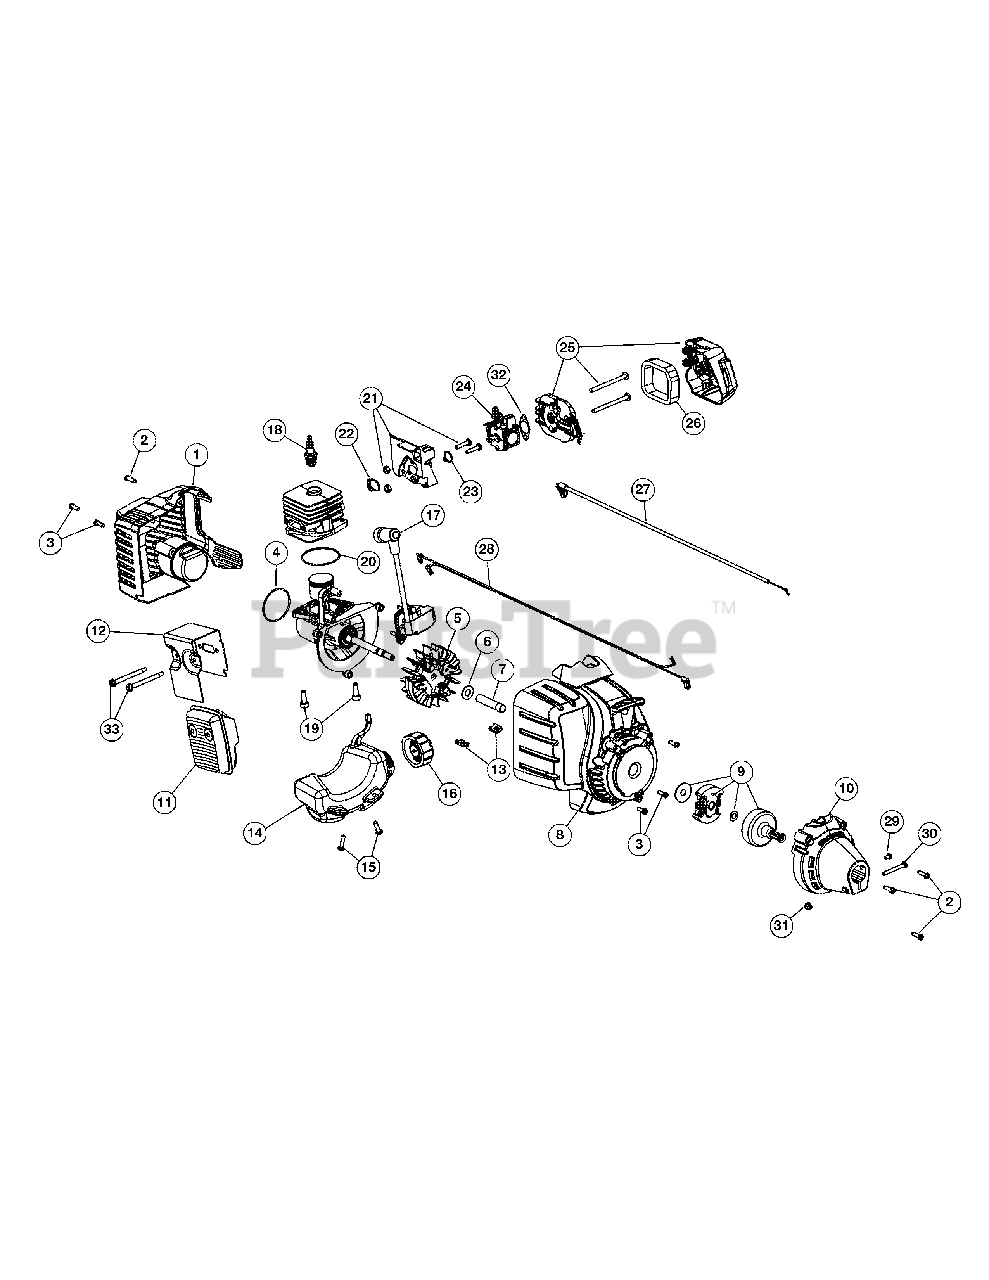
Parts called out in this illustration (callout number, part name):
1	Rear Cover Assembly (Incl. 2 & 3)
2	Cover Screw
3	Housing Screw
5	Flywheel Assembly
8	Starter Housing (Incl. 3 & 13)
9	Clutch Assembly
10	Clutch Cover (Incl. 2)
11	Muffler Assembly (Incl. 12 & 33)
12	Muffler Gasket
13	U-shaped Nut
14	Fuel Tank Assembly (Incl. 15 & 16)
17	Module Assembly
18	Spark Plug
19	Crankcase Bolt
20	Crankcase O-Ring
21	Insulator Assembly (Incl. 22 & 23)
22	Insulator O-Ring
23	Carburetor O-Ring
24	Carburetor
25	Aircleaner Cover Assembly (Incl. 26)
26	Aircleaner Filter
27	Throttle Cable
28	Lead Wires
29	Anti-rotation Screw
30	Clamp Screw
31	Clamp Nut
32	Air Cleaner Gasket
33	Muffler Screw
